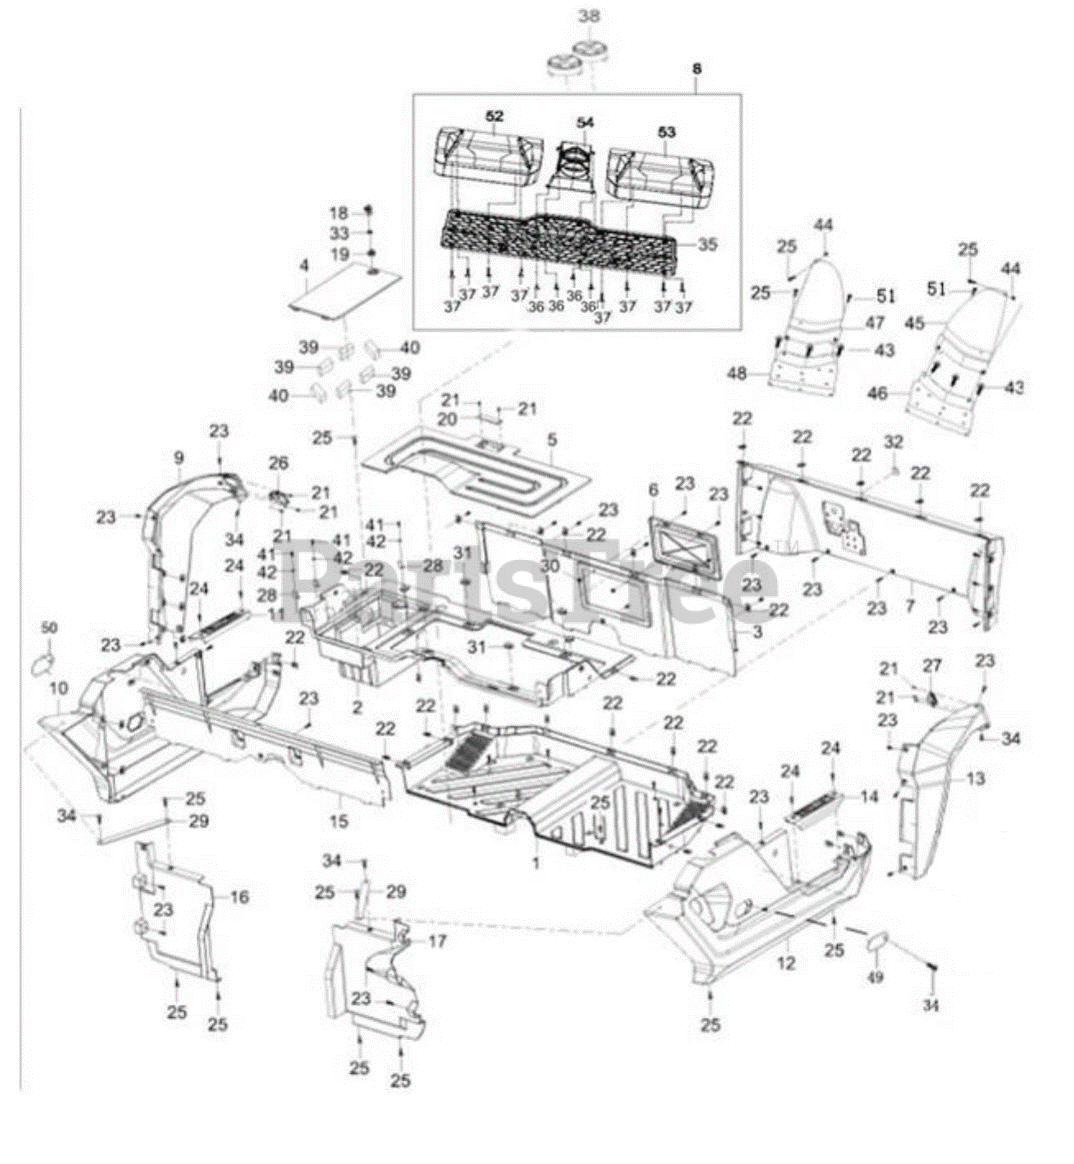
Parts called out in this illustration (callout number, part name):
2	SEAT SUPPORT I
3	SEAT BOX PANEL
4	BATTERY COVER
5	ENGINE COVER
6	COVER - BATTERY BOX
7	FIREWALL PANEL
8	BENCH SEAT (BOTTOM)
9	SIDE PANEL - FRONT LEFT
10	SIDE PANEL - MIDDLE LEFT
11	SIDE PROTECTOR - LEFT
11	SIDE PROTECTOR - LEFT (BLACK)
12	SIDE PANEL (MID) (RH)
13	SIDE PANEL - FRONT RIGHT (SILVER)
14	SIDE PROTECTOR - RIGHT (SILVER)
14	SIDE PROTECTOR - RIGHT (BLACK)
15	SEATING PROTECTOR
16	REAR MUDGUARD II
17	REAR FENDER
18	LOCK - BATTERY BOX COVER
19	RUBBER BATTERY COVER GROMMET
20	LOCK - ENGINE COVER
21	SCREW - CROSS HEAD SELF TAPPING
22	CLAMP NUT M6X6
23	SOCKET HEX FLAT HEAD BOLT M6X16
24	HEX HEAD FLANGE BOLT M6X20
25	SCREW M6X16
26	TURN LIGHT - FRONT LEFT
27	TURN LIGHT - FRONT RIGHT
28	STARTER RELAY BRACKET
29	SIDE PLATE SUPPORT I
30	HEX FLANG NUT M6
31	RUBBER WASHER
32	BRAKE PEDAL DUST PAD
33	FLAT WASHER 15x22x1
34	HEX HEAD CAP SCREW M6X16
35	BENCH SEAT BASE PAN
36	SCREW M6X12
37	SCREW M6X20 LG PLT HD
38	CUP HOLDER
39	BATTERY PAD 90x50x15
40	BATTERY PAD 90x50x15
41	CROSS RECESSED BOLT & WASHER ASM
42	PLAIN FLAT WASHER
43	HEXAGON FLANGE BOLT M6X16
44	LOCK NUT M6
45	FENDER GUARD BRACKET (UPPER RH)
46	FENDER GUARD BRACKET (LOWER RH)
47	FENDER GUARD BRACKET (LOWER LH)
48	FENDER GUARD BRACKET (UPPER LH)
49	ROCK SLIDER MOUNT COVER (RH)
50	ROCK SLIDER MOUNT COVER (LH)
51	SCREW M6X12
52	SEAT PAD-BOTTOM (RH)
53	SEAT PAD-BOTTOM (LH)
54	CENTER CONSOLE
